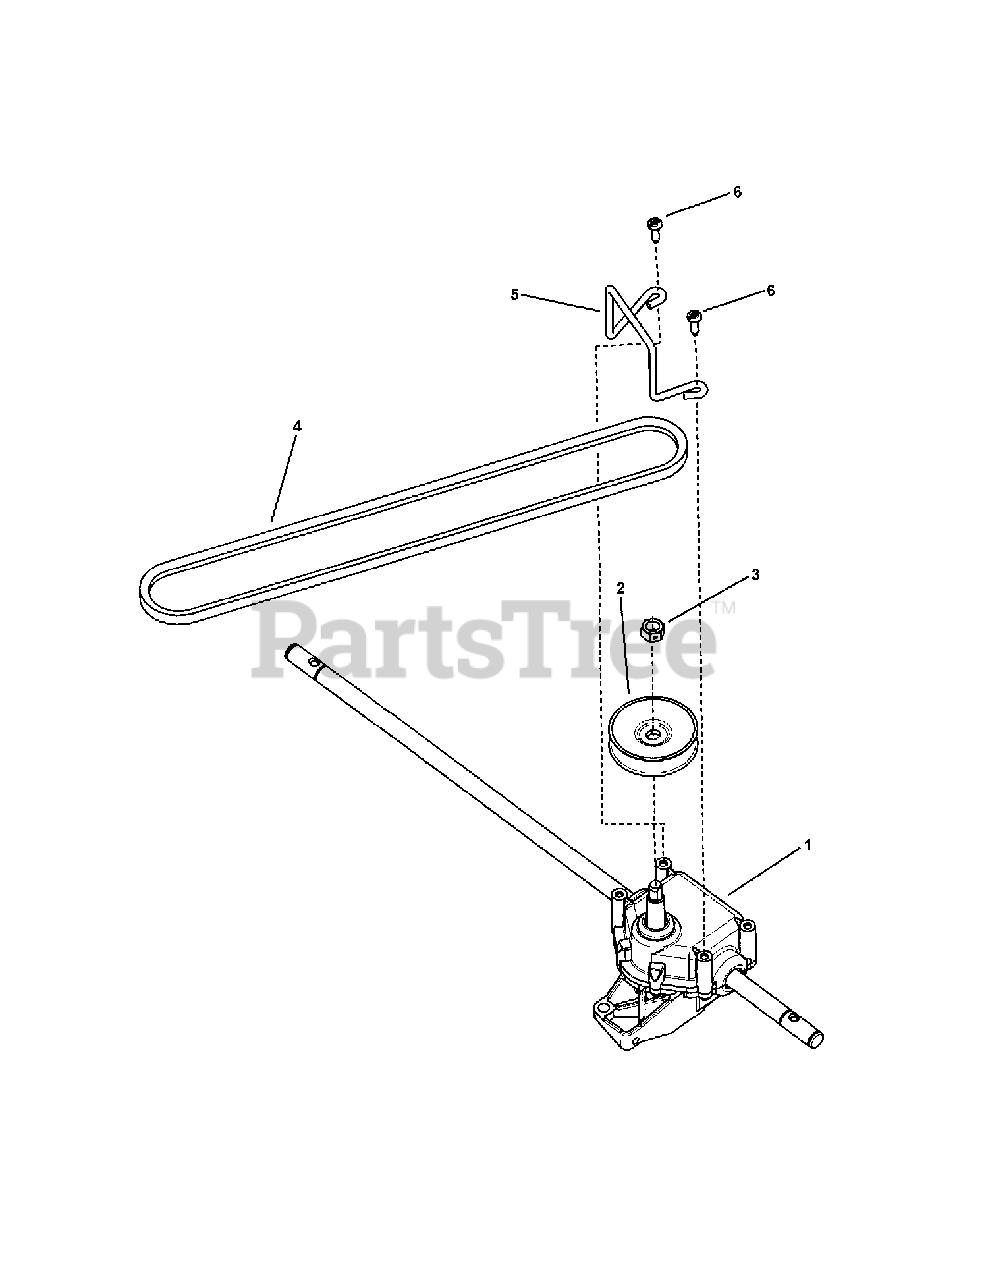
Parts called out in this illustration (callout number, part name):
1	TRANSMISSION, Variable Speed, Rear Wheel Drive
2	PULLEY, Transmission Variable Speed, LC WBM
3	NUT, 3/8-16 Hex Center Lock, YZ
4	BELT, 3L, Traction Drive, 22" WBM, RWD
5	BELT GUIDE, Transmission
6	SCREW, #10-16 x 3/4" Pan Head Self-Tap, Combo
